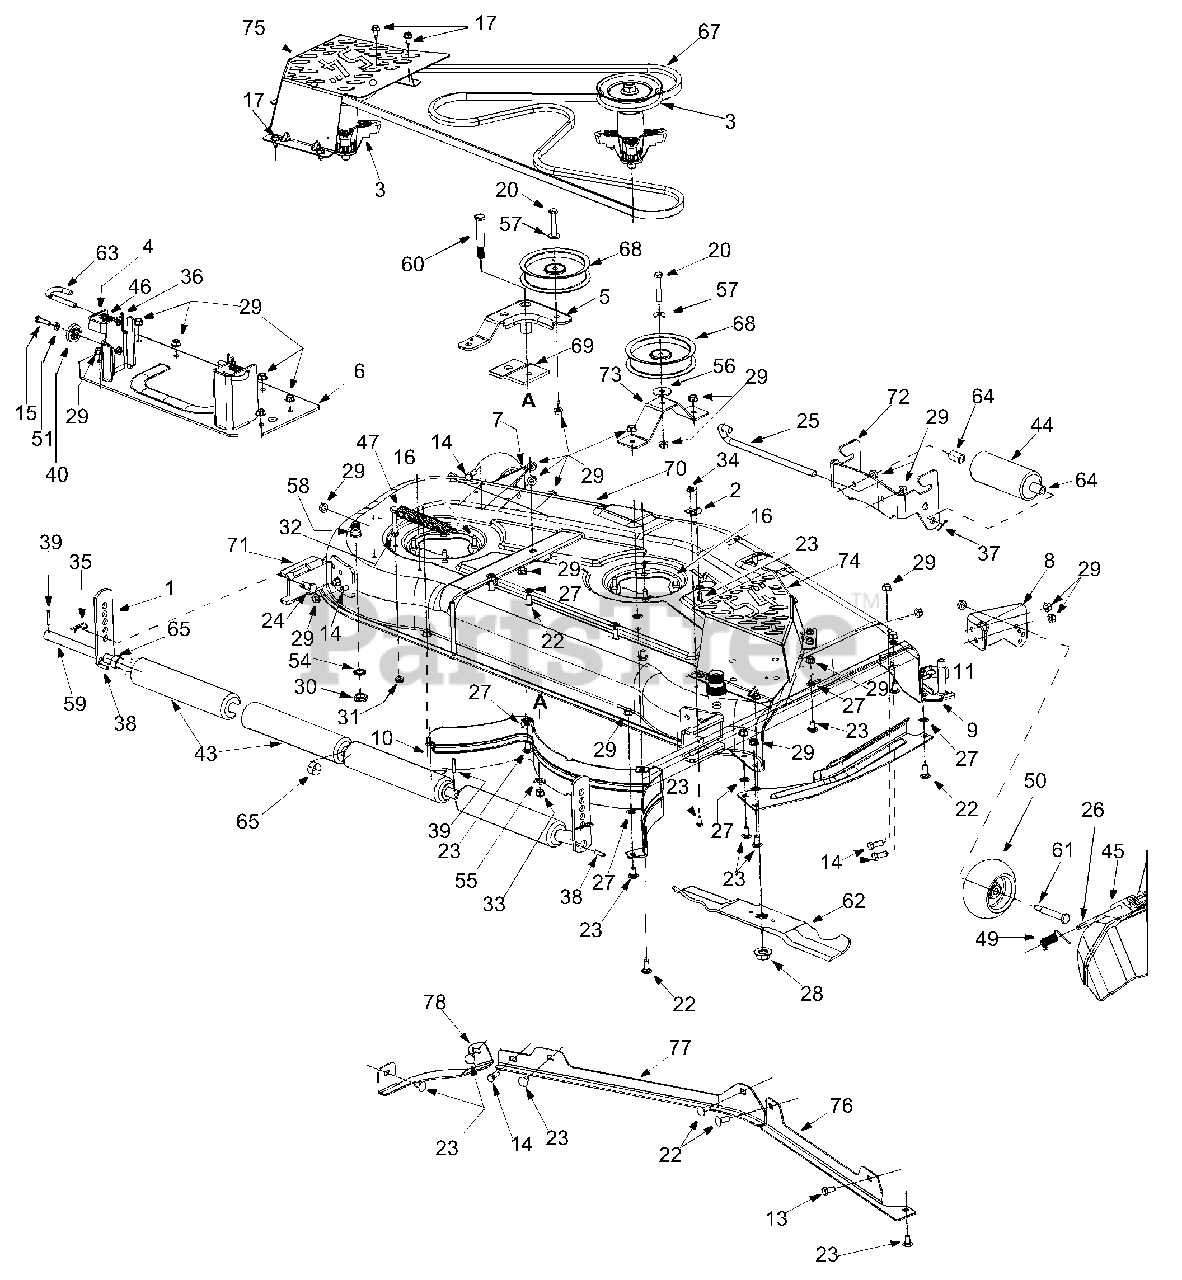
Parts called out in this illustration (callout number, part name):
2	Bracket, Hook, Retainer
3	Spindle Assembly, Pulley, 5.39 Dia x .5625
13	Hex Screw 3/8-16 x 0.75
14	Hex Screw 3/8-16 x 1.0
15	Hex Screw, 5/16-18 x 1.25
16	LD Screw 5/16-18 x 0.75
17	AB Screw 5/16-12 x 0.75
20	Hex Screw, 3/8-16 x 2.25
21	Hex Screw, 5/16-18 x 2.25
22	Bolt, Carriage, 3/8-16 x 1.0
23	Short Neck Carriage Bolt 3/8-16 x .75
24	Pin, Clevis, .50 Dia x .78
25	Pin, Roller, .5" Dia x 10.06
26	Pin, Hinge, Dia .375 x 14.06
27	Push Nut Retainer
28	Nut, Hex Flange, 5/8-18
29	Nut, Lock, 3/8-16
30	Hex Nut M16
31	Nut, Flange Lock, 5/16-18
32	Nut, Hex, 5/16-18, Gr5
33	Nut, Hex Lock, 1/2-13
35	Pin, Click, .092 x 1.64
36	Pin, Cotter, 1/8 x 1.25
37	Pin, Cotter, 3/32 x 1.25
38	Pin, Spring 1/4 Dia x 1.00
39	Cotter Pin
40	Adjustment, Deck, Gear
41	Water Nozzle Adaptor
43	Roller, Deck
44	Front Roller
45	Deflector, Chute
46	Spring, Compression, .406 x .531 x 1.75
47	Spring, Extension, .94 Dia x 6.74
48	Spring, Extension, 1.15 Dia x 5.99
49	Torsion Spring .44 I.d. x 2.10
50	Deck Wheel, 5" Dia.
51	Lock Washer
54	Lock Washer
55	Lock Washer
56	Flat Washer .406 ID X 1.5 x 11ga
57	Washer, Flat .38 ID x.93 OD x.110
58	Water Nozzle: Deck Wash-Out System
59	Shoulder Screw, .750 x .47.12
60	Shoulder Screw
61	Shoulder Screw
62	Blade, 18.50"
63	Deck Release Handle Rod, .375 Dia
64	Spacer .550 ID x .755 OD x 1.1
65	Spacer, .82 ID x 1.00 OD x .53
67	Belt, V-Type, B Section
68	Pulley, Idler, 5.0 Dia.
12650-4008	Height Adjuster - WINE RED (4008)
